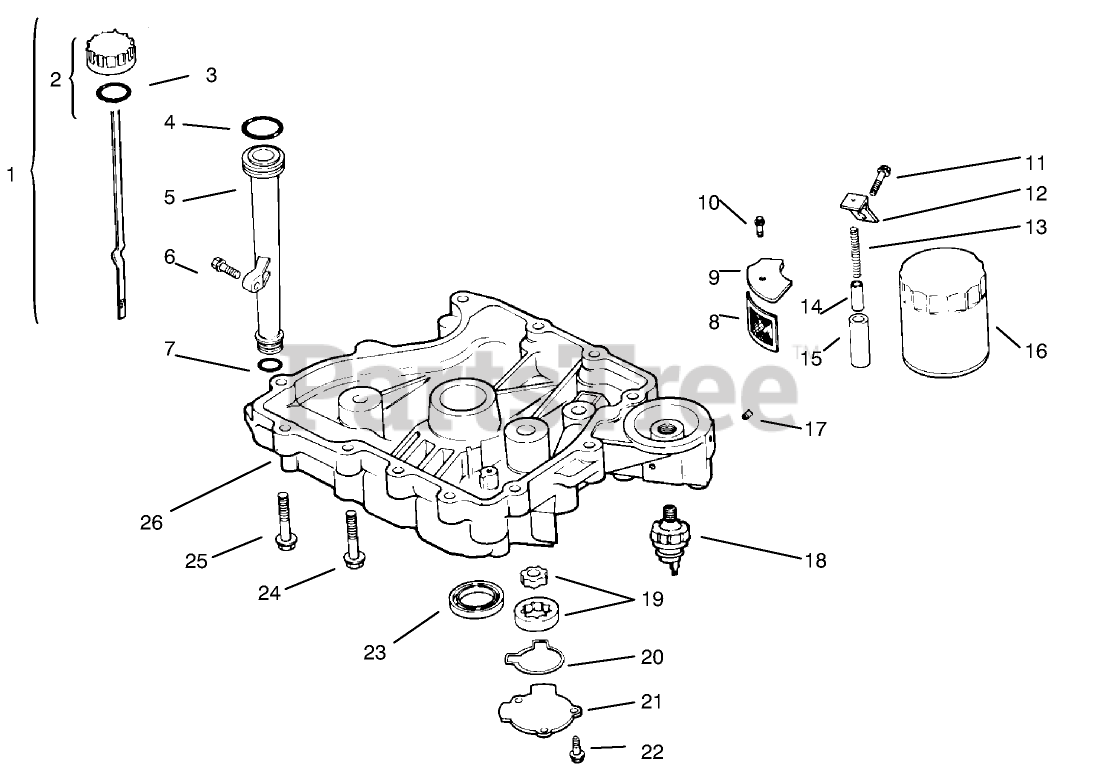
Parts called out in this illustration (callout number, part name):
1	Dipstick INC 2-3 (Only On: 72042, 72063, 72062, 72043)
2	Kit-Oil Fill Cap (Incl. Ref. #7)
3	ORing
4	O Ring-Upper Fill Tube (Only On: 72103)
5	Tube-Oil Fill (Only On: 72103, 72083)
6	Screw
7	O-Ring-Lower Fill Tube (Only On: 72042, 72063, 72062, 72043)
8	Screen-Oil Pickup
9	Cover-Oil Pickup Screen (Only On: 72042, 72063, 72062, 72043)
10	Screw M5x0.8x16 (Only On: 72042, 72063, 72062, 72043)
11	Screw M10x1.5x25 (Only On: 72042, 72063, 72062, 72043)
12	Bracket-Oil Pump Relief (Only On: 72042,72043,72062,72063)
13	Spring-Oil Relief Valve (Only On: 72042,72043,72062,72063)
14	Piston-Oil Relief Valve (Only On: 72042, 72063, 72062, 72043)
15	Body-Oil Relief Valve (Only On: 72042, 72063, 72062, 72043)
16	Filter-Oil
17	Plug
18	Switch-Oil Pressure
19	Pump-Oil (Only On: 72042, 72063, 72062, 72043)
20	O Ring-Oil Pump Cover (Only On: 72042,72043,72062,72063)
21	Cover-Oil Pump (Only On: 72042,72043,72062,72063)
22	Screw M5x0.8x16 (Only On: 72042, 72063, 72062, 72043)
23	Seal-Crankshaft (Only On: 72042, 72043, 72062, 72063)
24	Screw
25	Screw M8x1.25x45 (Only On: 72103, 72083)
26	Pan-Oil (Only On: 72042,72043,72062,72063)
